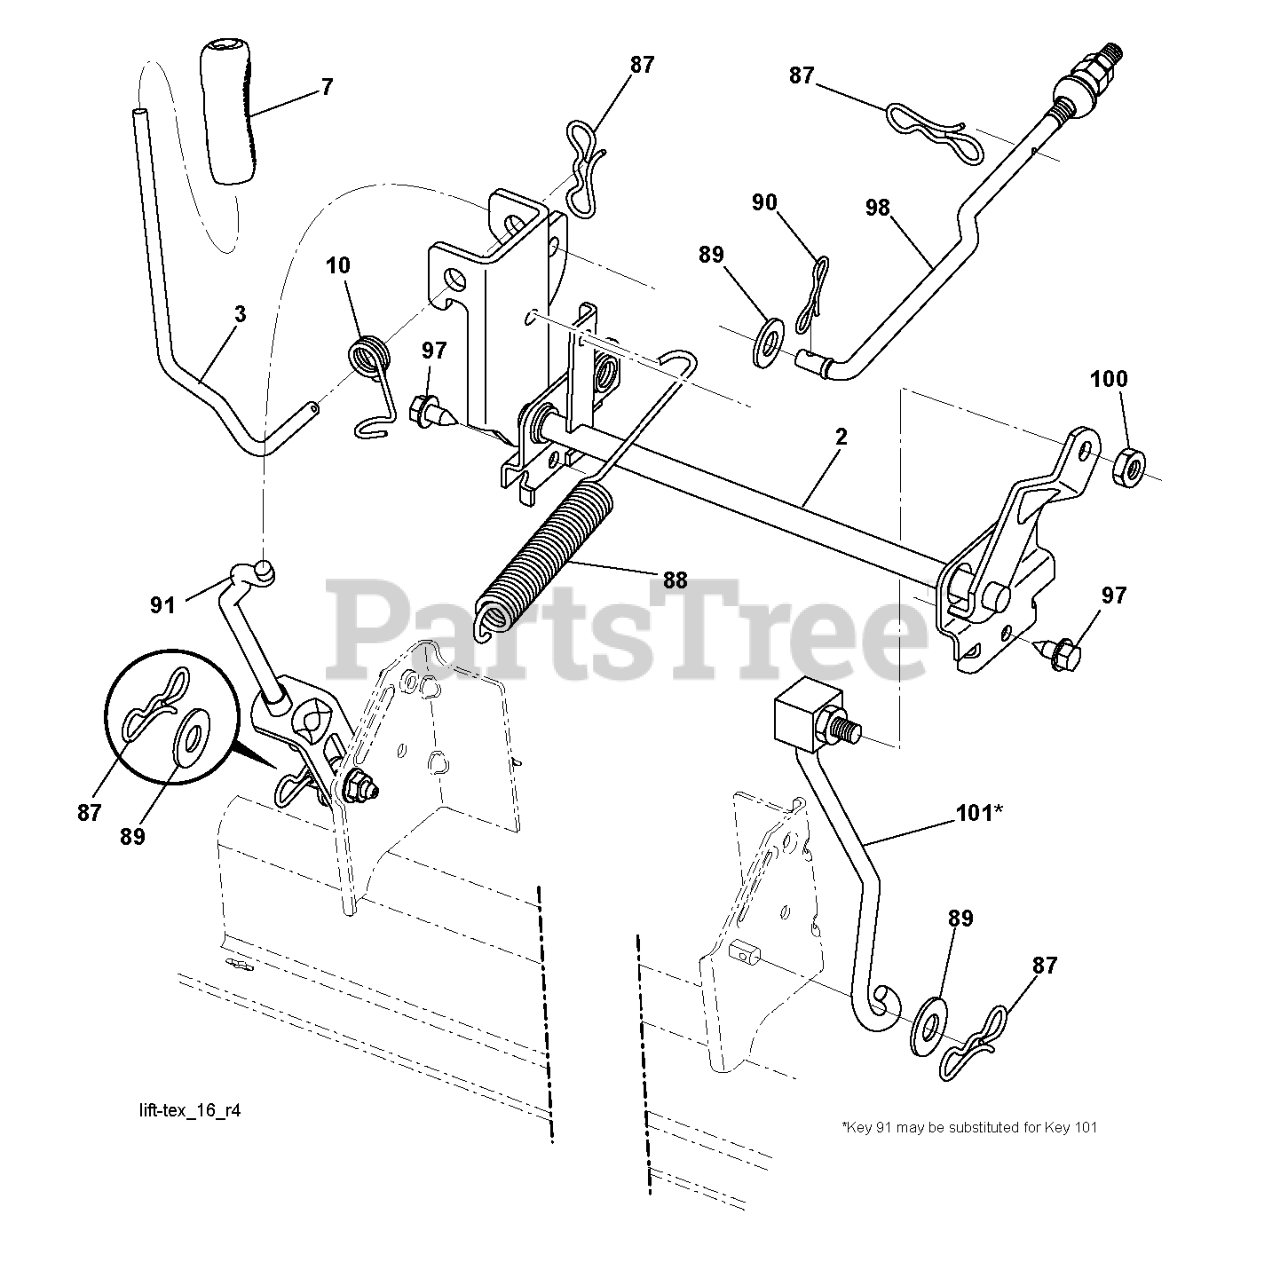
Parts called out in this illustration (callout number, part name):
2	SHAFT.ASM.CROSS.LIFT
3	LEVER.LIFT.HANDLE.GT
7	GRIP.HANDLE.LIFT.PVC.BLACK
10	SPRING.TORSION.LIFT.HANDLE
87	PIN.COTTER.7/16.BOW TI.
88	SPRING.LIFT.ASSIST
89	WASHER.CLEAR.ZINC
90	PIN.COTTER.5/16.BOW TI
91	LINK.ASM.LIFT.REAR
97	SCREW, 3/8-16X3/4
98	LINK.ASM.SUSP.FRONT.MW
100	LOCKNUT
101	LINK.ASM.LIFT.FIXE.38/42/46"
